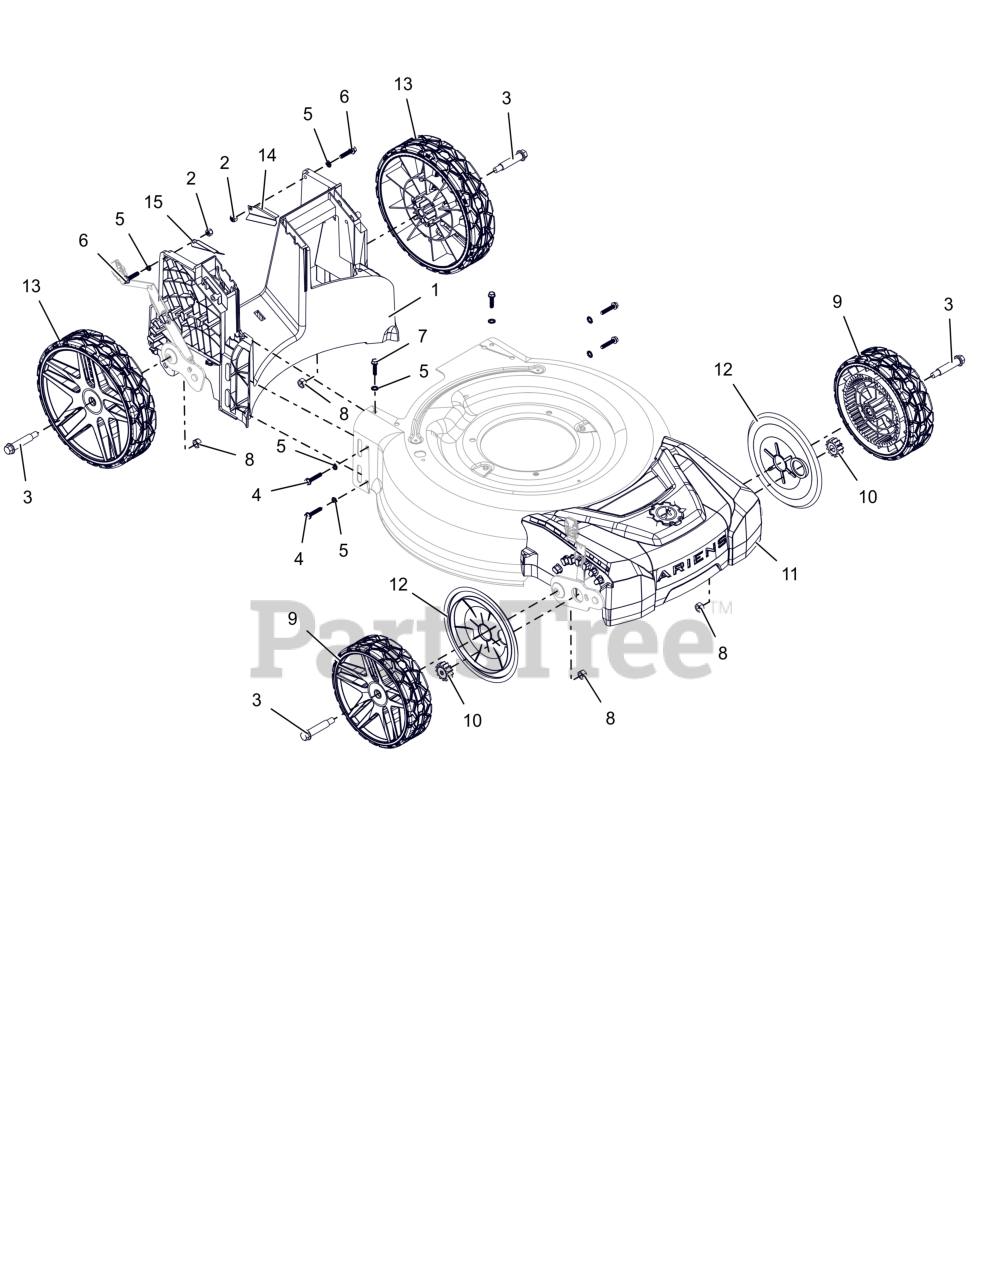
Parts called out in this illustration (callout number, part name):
1	ASM, REAR BAFFLE-FWD
2	NUT, NYLOC 1/4-20
3	BLT, SHLDR HWH .325X1.981X 3/8-16
4	SCR, HI-LO HWH 1/4-15 X 1.25
5	WSHR-LK-EXT, .256X.510X.028
6	BLT, HEX 1/4-20 X 1.125
7	SCR, HI-LO HWH 1/4-15 X 1.00
8	NUT-JAM .375-16 HIGH STRENGTH
9	WHEEL, MOLDED GEAR 8"
10	GEAR, FWD SPUR
11	COVER, FRONT
12	COVER, DUST - 8"
13	WHEEL, 10" - DARK GRAY
14	BRKT, LH DOWNWARD (BLACK)
15	BRKT, RH DOWNWARD (BLACK)
